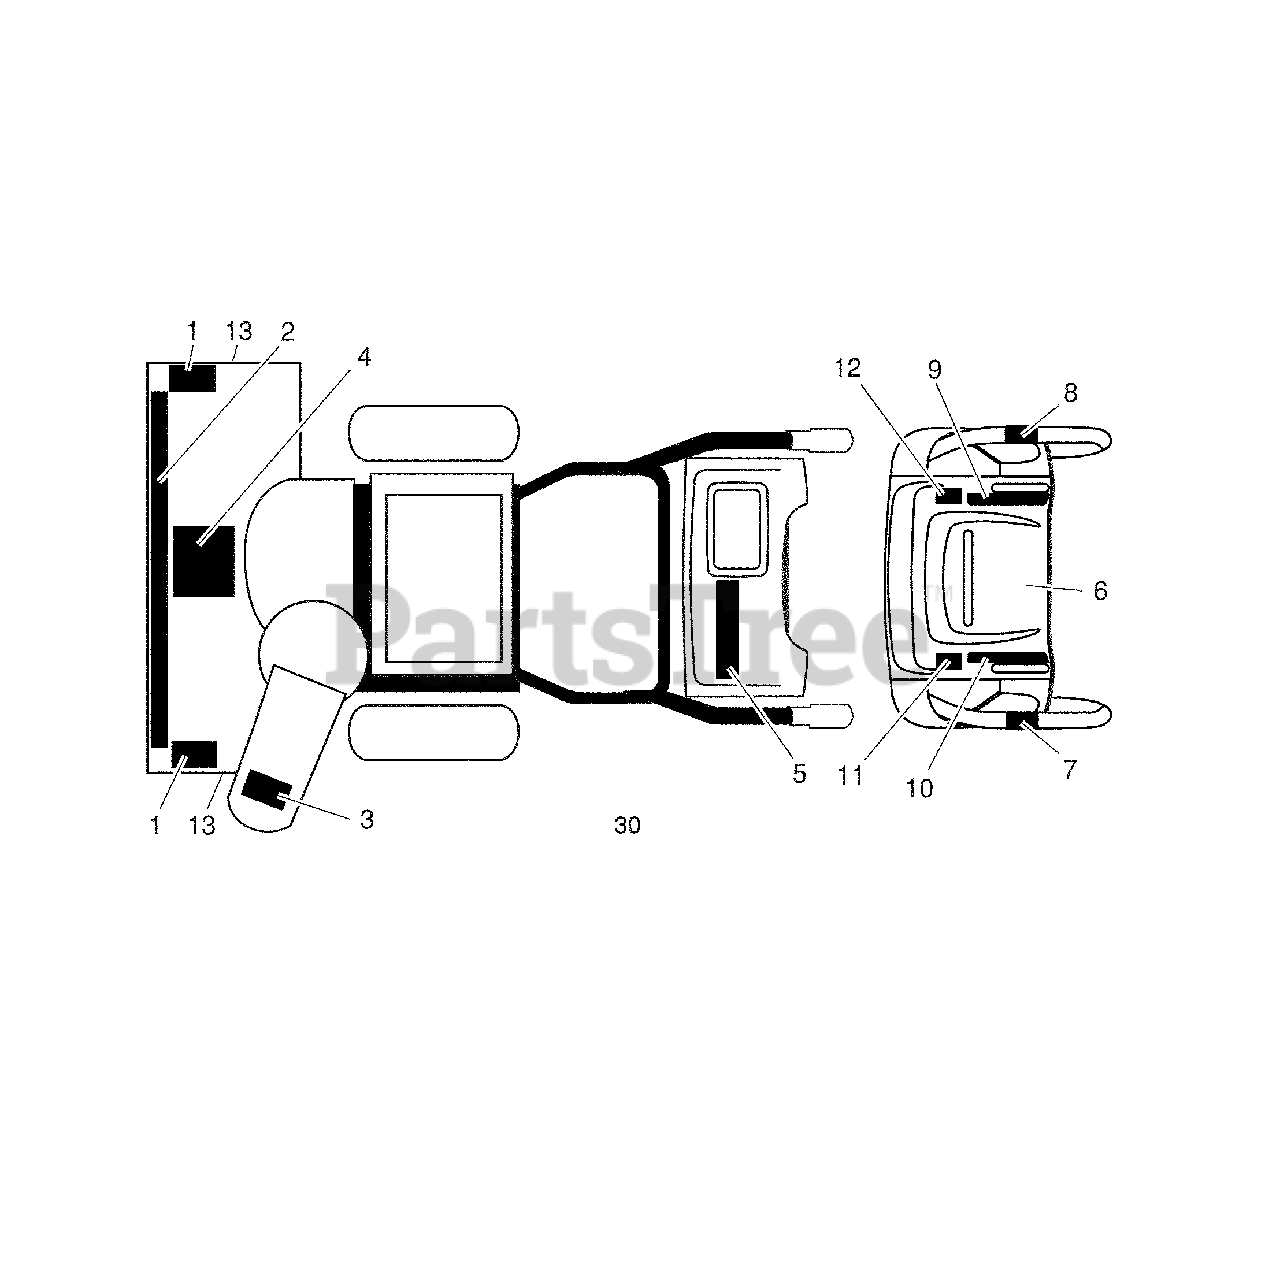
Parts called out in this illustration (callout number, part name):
1	Decal, Danger
2	Decal, Husqvarna
3	Decal, Danger, Deflector
4	Decal, Danger
5	Decal, Husqvarna, 10527SBE
6	Decal, Instruction
7	Decal, Traction Lever
8	Decal, Auger Lever
9	Decal, Speed Control
10	Decal, Remote Deflector
13	Decal, Husqvarna, Crown
